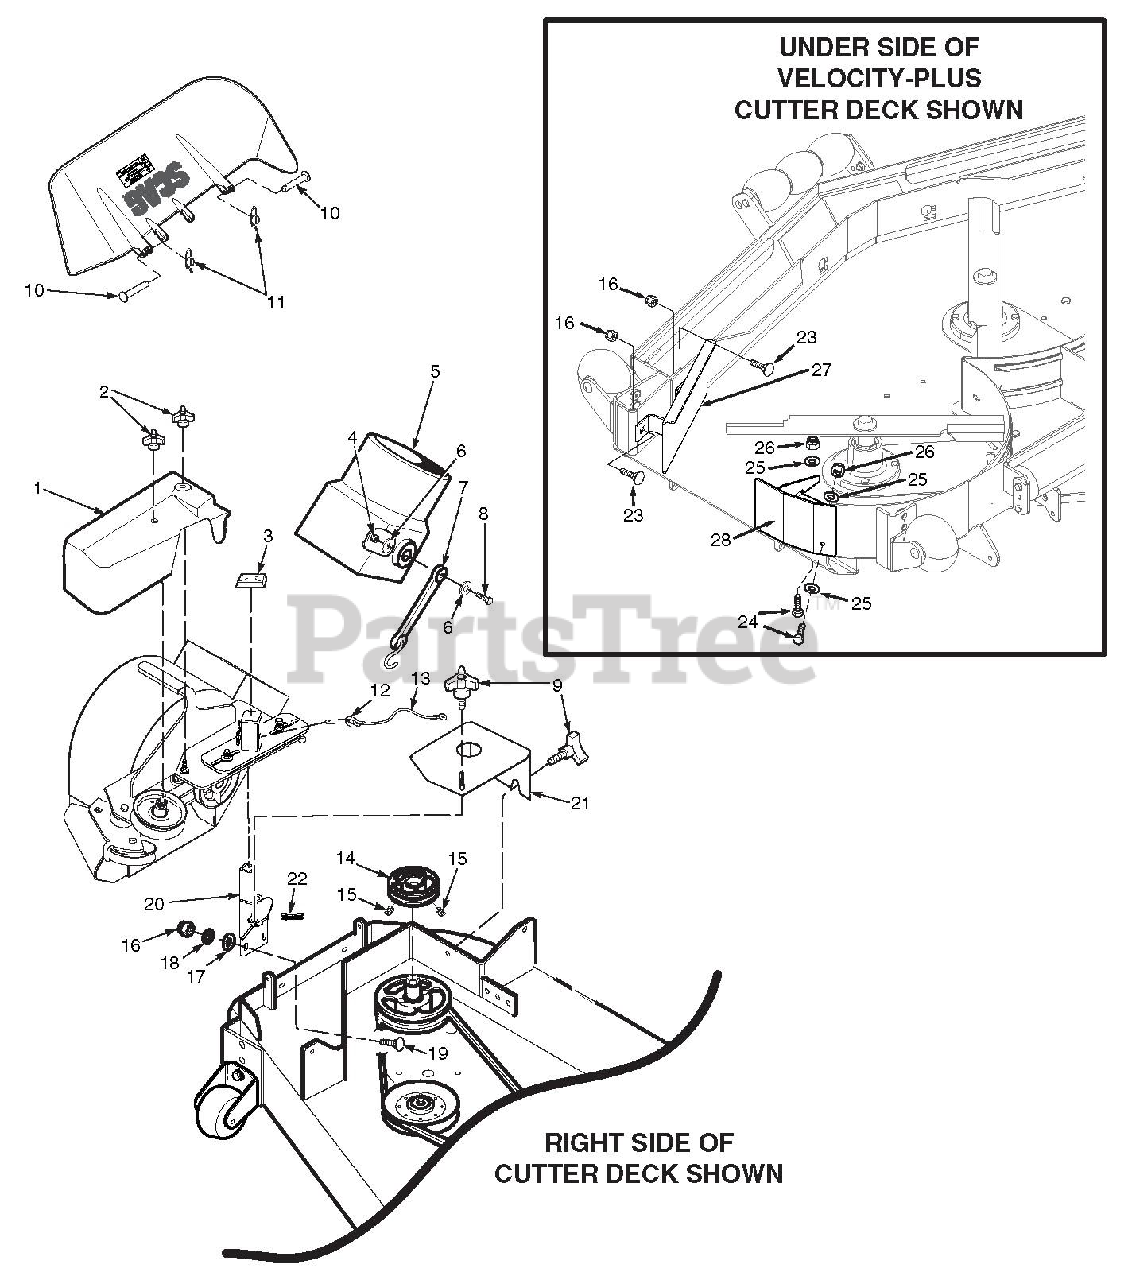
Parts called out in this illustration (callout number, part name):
1	Belt Cover, GC-STT - 61"
1	Belt Cover, (STT-52 & STTII-52)
2	Wingnut, Plastic 3/8" Small
3	Cap, Square Vinyl
4	Nut, Elastic Stop 1/4-20
5	Adapter, Blower GC-STT
6	Flatwasher, 1/4-.312 x .750 x .065
7	Rubber Strap 7-3/4"
8	Bolt, Hex Head 1/4-20 x 1-1/4"
9	Knob W/Stud, 3/8-16 x 1-1/4"
10	Clevis Pin, 5/16 x 1-1/2"
11	Pin, Rue Cotter 5/16 Dia.
12	Pin, Ring 1/2 x 2-1/4"
13	Lanyard
14	Pulley, 5-1/2" Dia. - 1.125" Bore
14	Pulley, 4.0" Dia. - 1.125" Bore, (STT-52 & STTII-52)
15	Setscrew, 5/16-18 x 3/8"
16	Nut, Elastic Stop 3/8-16
16	Nut, Elastic Stop 1/2-13, (STT-52 & STTII-52)
17	Lockwasher, 3/8"
18	Flatwasher, 3/8-.391 x .938 x .105
19	Bolt, Carr. 3/8-16 x 1-1/4" Grade 5
19	Bolt, Hex Head 1/2-13 x 1-1/2", (STT-52 & STTII-52)
20	Mounting Post Weldment, Blower
20	Mounting Post Weldment, Blower, (STT-52 & STTII-52)
21	Belt Cover Assembly, GC-STT-61V w/Cap
21	Belt Cover, (STT-52 & STTII-52)
23	Bolt, Carriage 3/8-16 x 1"
24	Bolt, Hex Head 5/16-18 x 1"
25	Flatwasher, 5/16-.375 x .875 x .083
26	Nut, Elastic Stop 5/16-18
27	Baffle Weldment, 61V Deck
27	Baffle Weldment, 52V Deck
28	Baffle, Turbo 61" Deck
28	Baffle, Turbo 52" Deck
